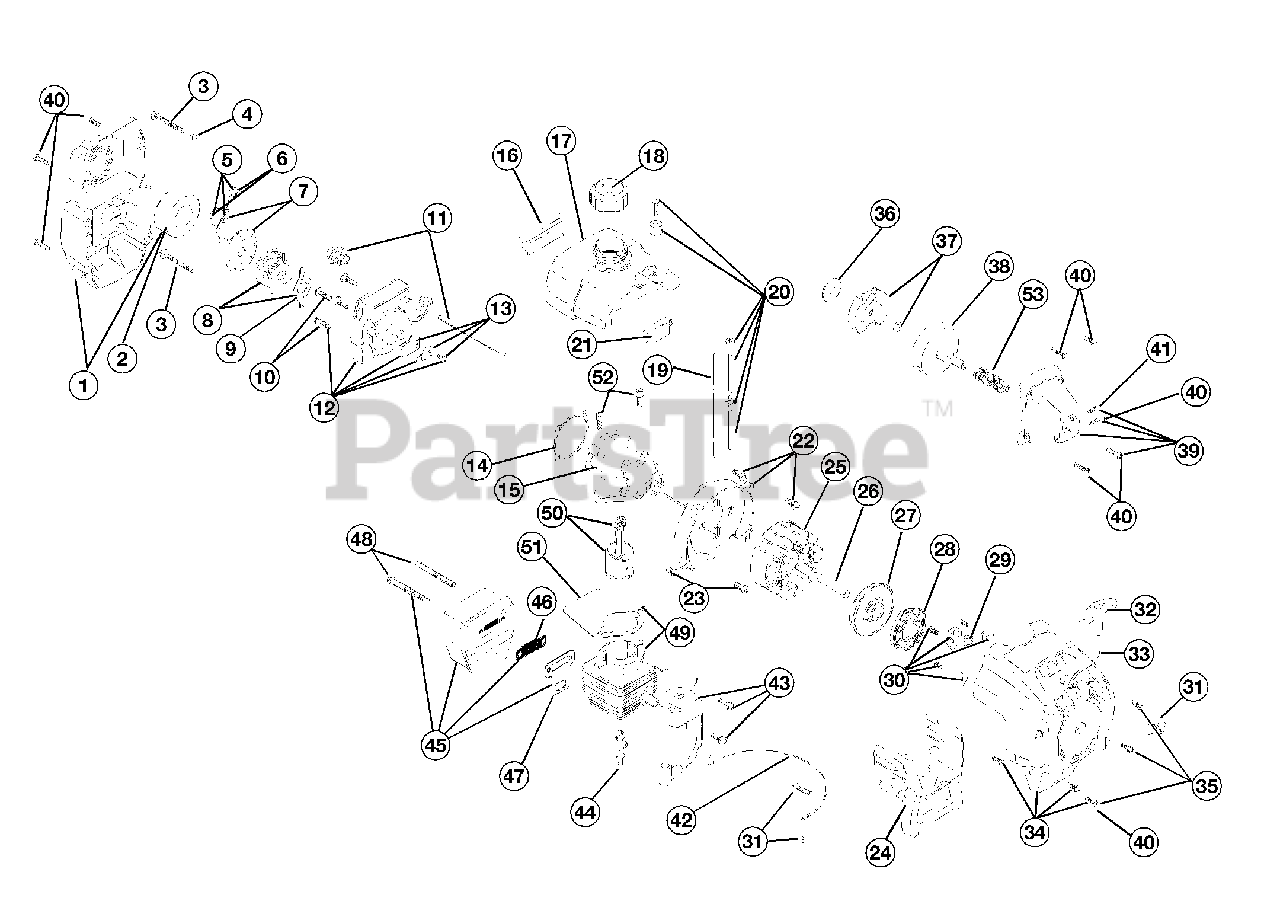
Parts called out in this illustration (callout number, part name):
1	Air Cleaner/Muffler Cover Assembly
2	Air Cleaner Filter
3	Carburetor Mounting Screw Assembly
4	Wavey Washer
5	Choke Lever Assembly
6	Choke Knob and Screw
7	Choke Lever and Plate
8	Carburetor Assembly
9	Carburetor Gasket
10	Carb Mount Screw
11	Primer and Hose Assembly
12	Carb Mount Assembly
13	Reed Assembly
14	Carburetor Mount Gasket
15	Crank Case Service Assembly
16	Rear Mounting Pad
17	Fuel Tank Assembly
18	Fuel Cap Assembly
19	Fuel Return Line
20	Fuel Line Assembly
21	Front Mounting Pad
22	Shroud Assembly
23	Shroud Screw
24	Shroud Extension and Stand
25	Flywheel Assembly
27	Recoil Pulley Assembly
28	Recoil Spring
29	Rope Guide
30	Pulley Retainer Assembly
31	Switch Assembly
32	Pull Handle
34	Starter Housing Assembly
35	Housing Screw
36	Clutch Washer
37	Clutch Rotor Assembly
38	Clutch Drum Assembly
39	Clutch Cover Assembly
41	Anti-Rotation Screw
42	Wire Lead
43	Module Assembly
44	Spark Plug
45	Muffler Assembly
46	Spark Arrestor Screen
47	Exhaust Gasket
48	Muffler Mounting Bolt Assembly
49	Cylinder Assembly
50	Piston and Rod Assembly
51	Cylinder Gasket
52	Cylinder Bolt
